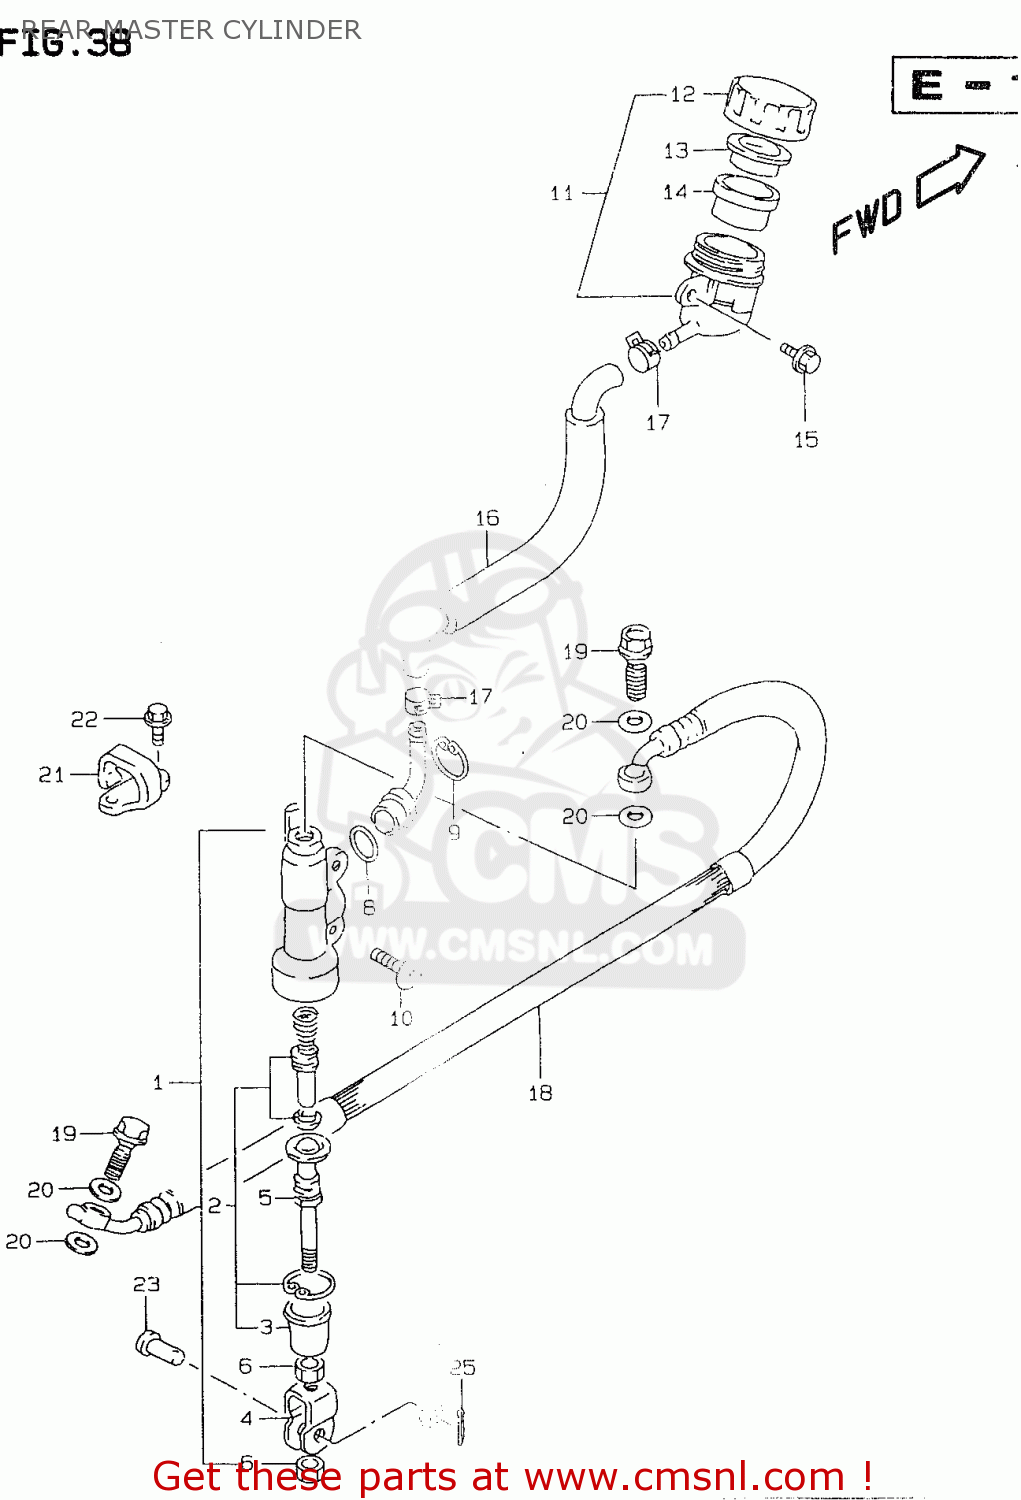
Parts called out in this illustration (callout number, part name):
1	CYLINDER ASSY,RR MASTER
2	PISTON/CUP SET
3	BOOT
4	YOKE
5	ROD,PUSH
6	NUT
7	CONNECTOR
8	O RING
9	CIRCLIP
10	SCREW(6X16)
11	TANK ASSY,RR BRAKE RESERVOIR
12	CAP
13	PLATE
14	DIAPHRAGM
15	BOLT
16	HOSE,RESERVOIR TANK
17	CLAMP,RESERVOIR HOSE
18	HOSE,RR BRAKE
19	BOLT UNION
20	WASHER(10X15X1.5)
21	GUIDE,RR BRAKE HOSE
22	SCREW
23	PIN(8X20)
24	WASHER(8.5X13X1.6)
25	PIN
